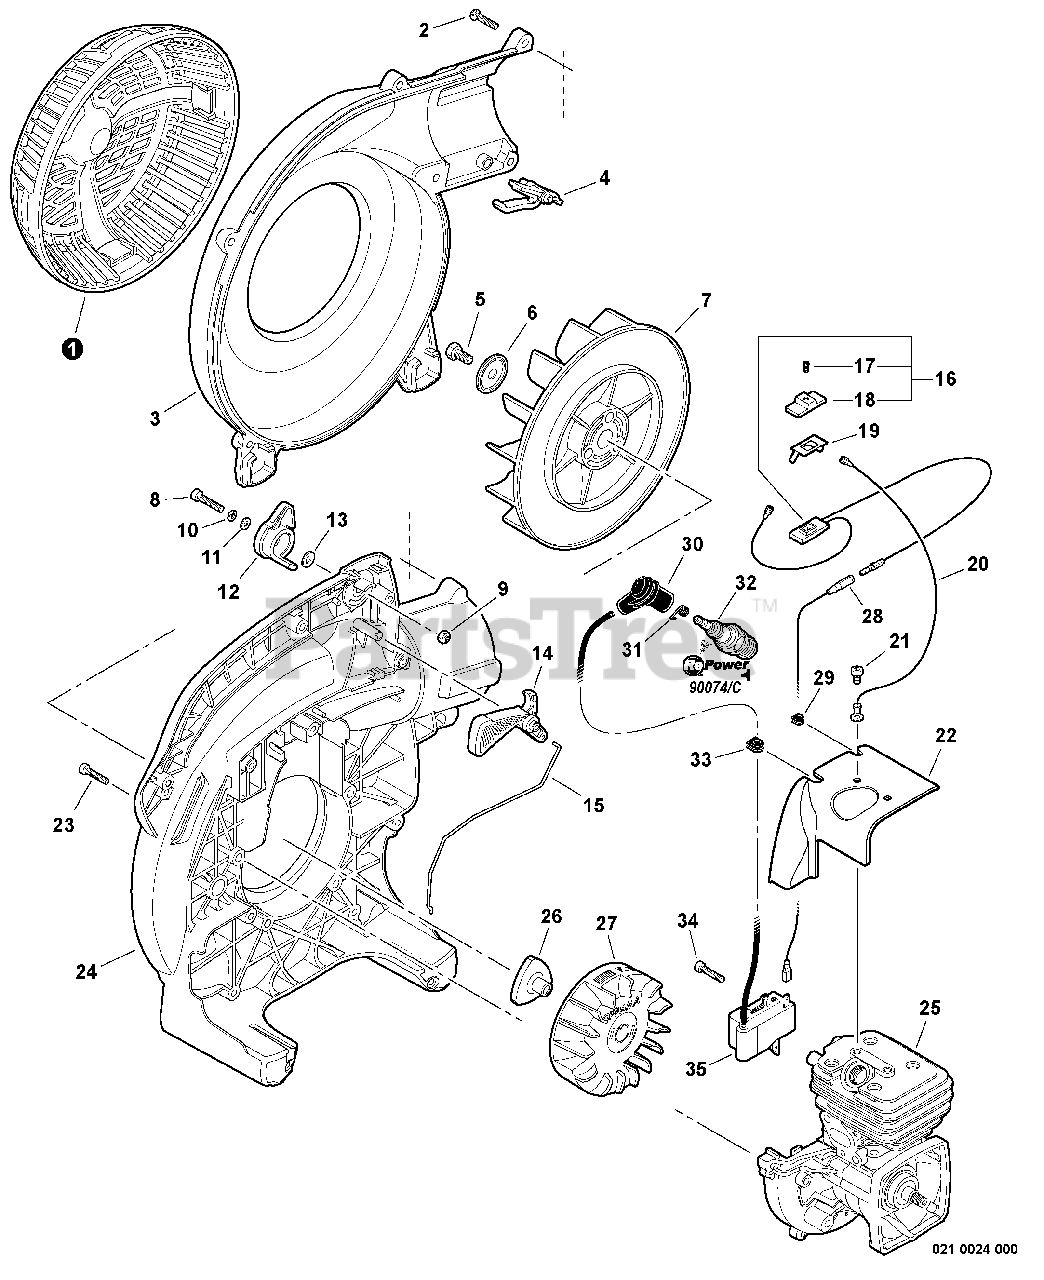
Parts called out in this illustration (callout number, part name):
1	GUARD, FAN
2	BOLT, TORX 5×20
3	COVER, FAN
4	LOCK, TUBE
5	BOLT 8×14
6	WASHER 8.2×31×0.8
7	FAN, BLOWER
8	BOLT, TORX 5×25
9	NUT, LOCK M5
10	WASHER, SPRING 5
11	WASHER 5.3×10×1
12	CONTROL, THROTTLE
13	WASHER 5.5×12×0.8
14	TRIGGER, THROTTLE
15	ROD, THROTTLE
16	SWITCH ASSY, ON-OFF
17	SCREW 3×10
18	KNOB, SWITCH
19	TERMINAL, LEAD
20	BOLT, TORX 5×8
21	LEAD L= 210 MM
22	SHIELD, CYLINDER
23	BOLT, TORX 4×20
24	CASE, FAN
25	SHORT BLOCK
26	HUB, FAN
27	FLYWHEEL
28	LEAD L= 85 MM
30	CAP, SPARK PLUG
31	TERMINAL, SPARK PLUG
32	SPARK PLUG - BPM8Y
32	SPARK PLUG - BPMR8Y
34	BOLT, TORX 4×20
35	COIL, IGNITION
36	TUNE-UP KIT - REPOWER
